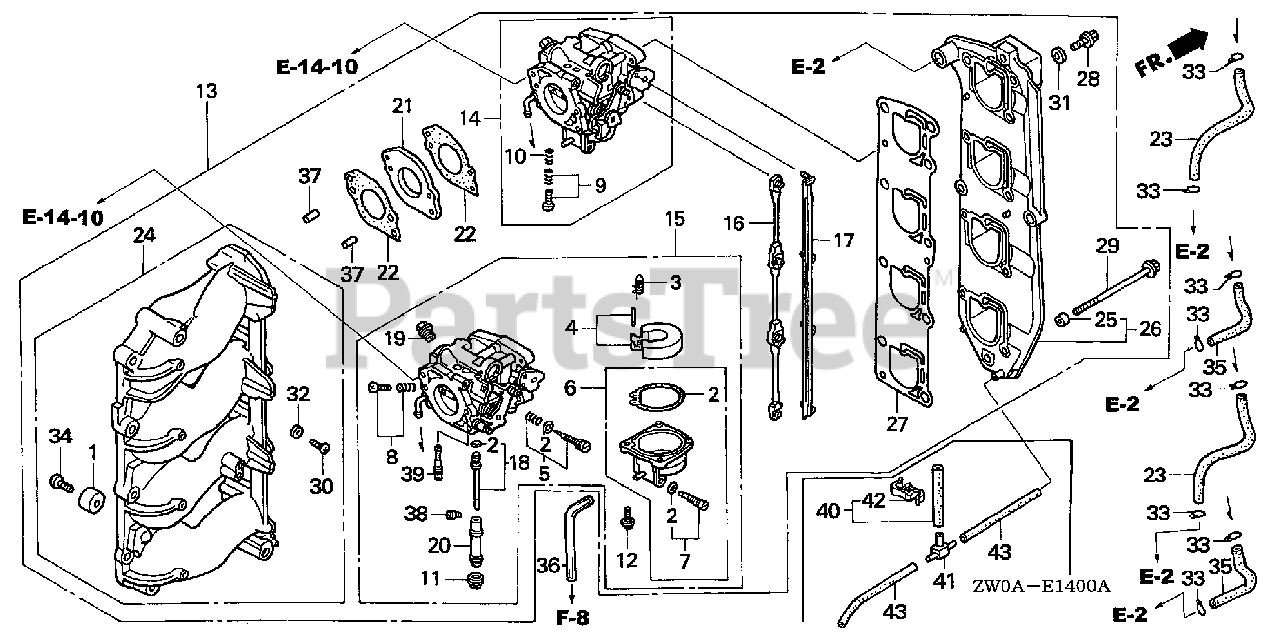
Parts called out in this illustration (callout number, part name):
1	METAL, ANODE
2	GASKET SET
3	VALVE SET, FLOAT
4	FLOAT SET
6	CHAMBER SET, FLOAT
7	SCREW SET, DRAIN
11	SCREW, PLUG
12	SCREW-WASHER
13	CARBURETOR ASSY. (BG35F C) *NH8* (DARK GRAY)
14	CARBURETOR ASSY. (#1 #2 #3)
15	CARBURETOR ASSY. (#4)
16	LEVER, LINK
17	LINK, CHOKE
18	JET SET (#42)
19	BOLT, HOLDING
20	NOZZLE, MAIN
21	INSULATOR, CARBURETOR
22	GASKET, CARBURETOR
23	TUBE A, FUEL
24	MANIFOLD ASSY., IN. *NH8* (DARK GRAY)
25	COLLAR, DISTANCE (6.5X11X7.5)
26	PLATE, MUFFLER (CARBURETOR NO.)
27	GASKET, MUFFLER PLATE
28	BOLT, FLANGE (6X20)
29	BOLT, FLANGE (6X106)
30	SCREW, PAN (5X10)
31	WASHER, PLAIN (6MM)
32	WASHER, SEALING (5MM)
33	CLIP, TUBE (B10)
34	SCREW, PAN (6X18)
35	BULK HOSE, FUEL (5.5X3000) (5.3X175)
36	BULK HOSE, VINYL (3.5X6.5X8000) (3.5X6.5X230)
37	ROLLER (6X15)
38	JET, MAIN (#130)
38	JET, MAIN (#132)
38	JET, MAIN (#135)
39	JET, SLOW (#40)
40	TUBE ASSY., DRAIN
41	JOINT, MUFFLER DRAIN
42	CLIP, R. BRAKE WIRE
43	BULK HOSE, VINYL (4X7X8000) (4X7X140)
